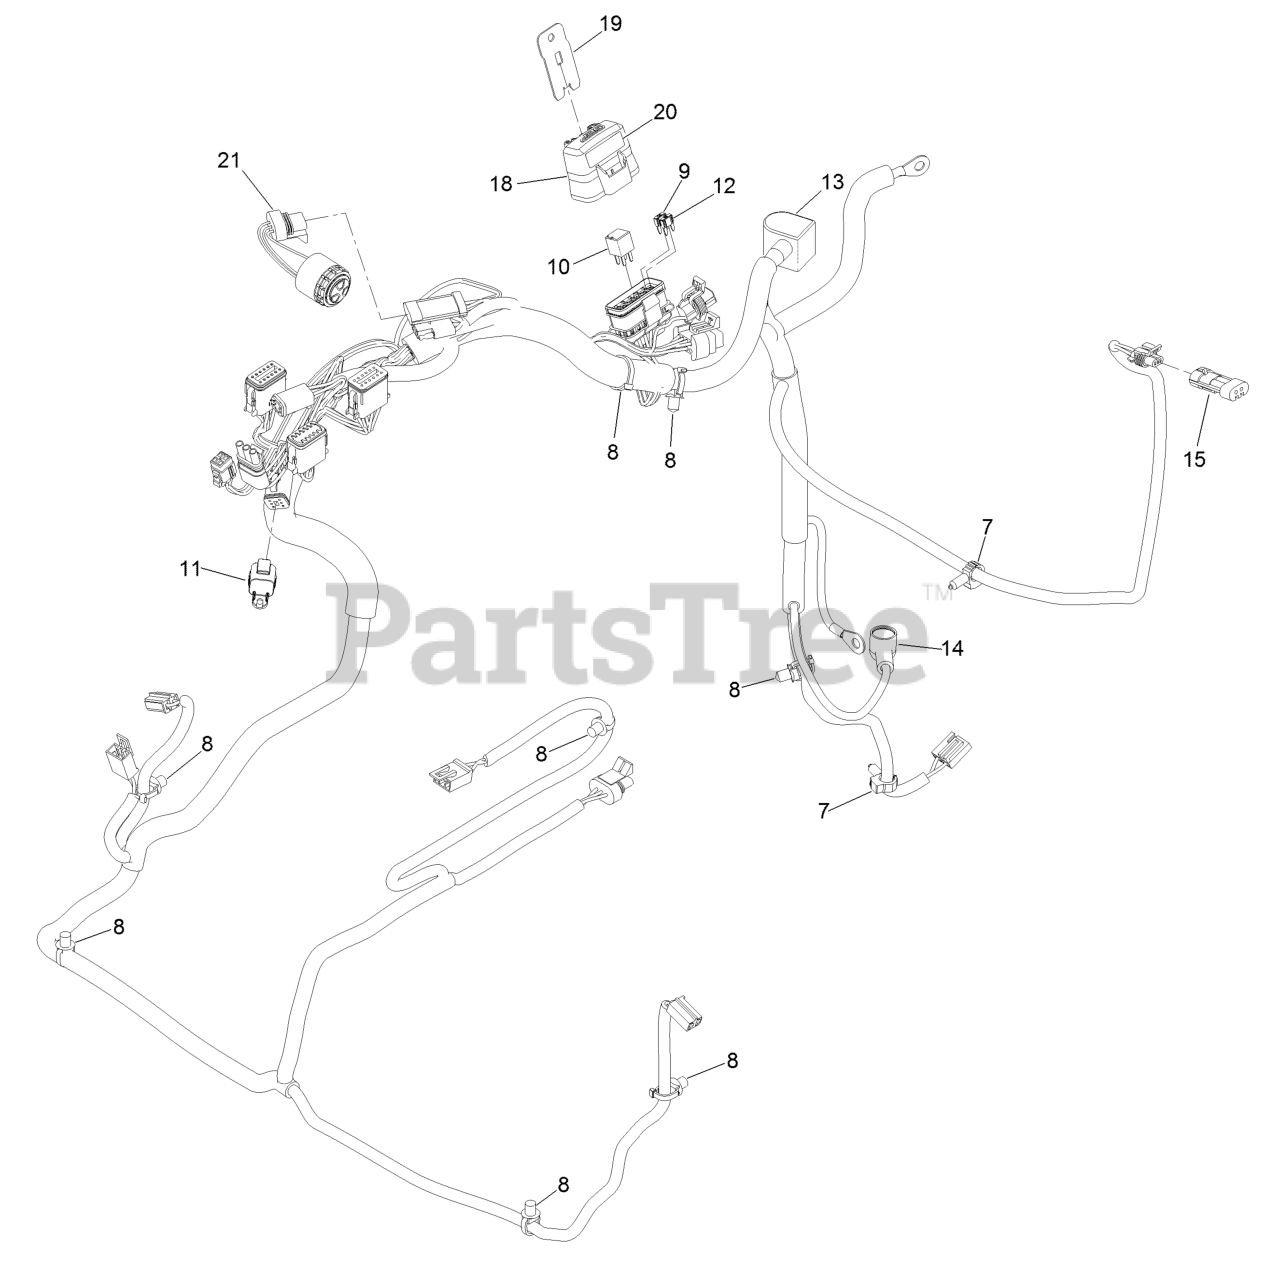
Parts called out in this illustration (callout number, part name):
7	Clip-Harness
8	Clip-Tie
9	Fuse-Mini Blade, 20 Amp
10	Relay-Micro
11	Cap-Plug, 6 Way
12	Fuse-Mini Blade, 15 Amp
13	Insulator-Battery
14	Insulator-Solenoid
15	Connector
18	Cover-Block, Fuse
19	Clip-Mounting
20	Decal-Fuse
21	Alarm-Dual Tone
